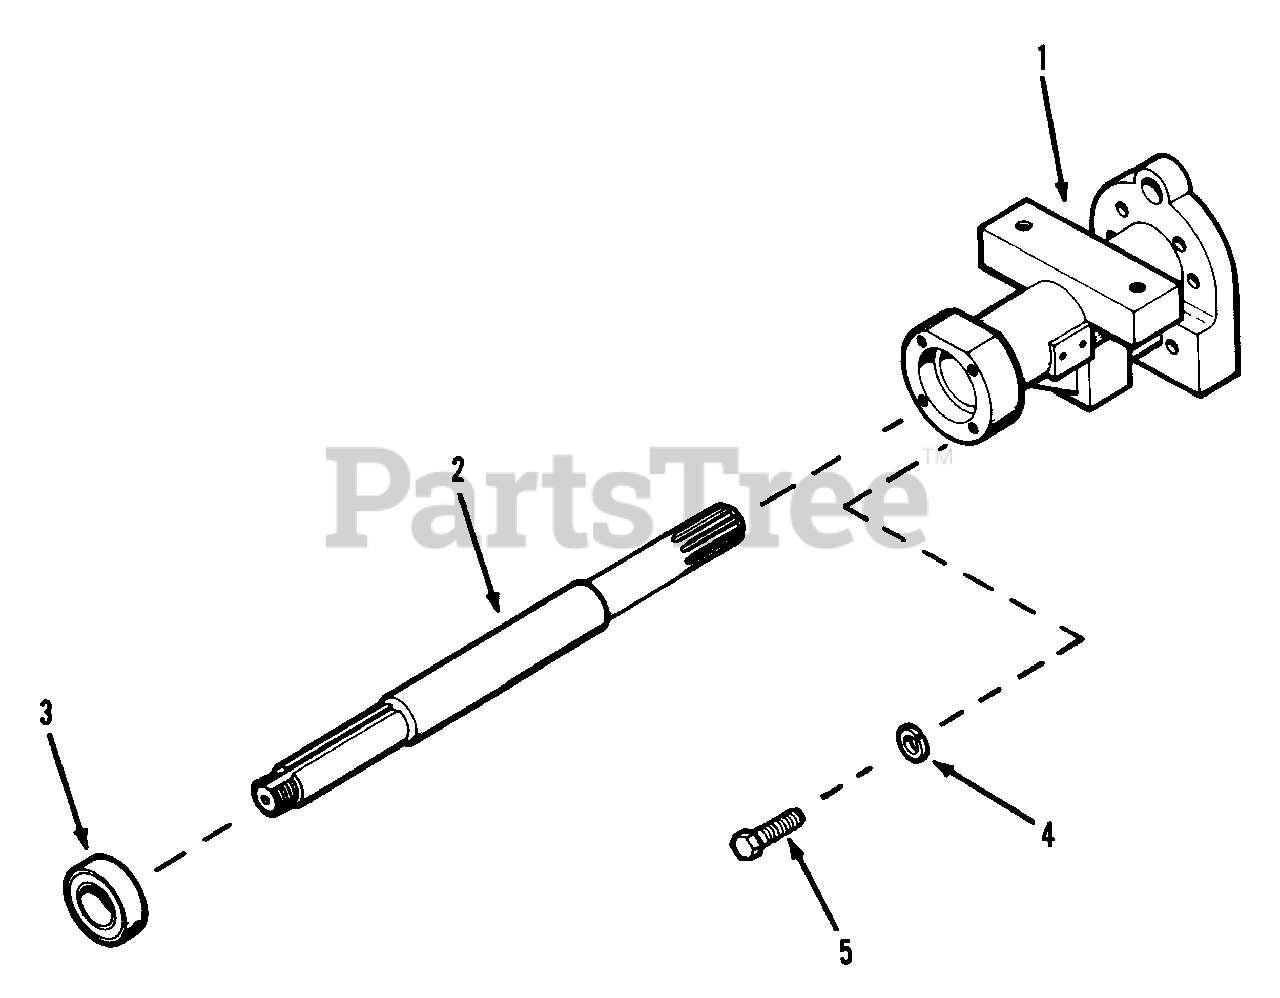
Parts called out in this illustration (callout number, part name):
1	HOUSING, Axle, 8-3/8" long
2	AXLE, 16-9/16"long
3	BEARING, Ball
4	FLATWASHER 3/8
5	SCREW, Hex Hd. Cap, 3/8-16 x 1
